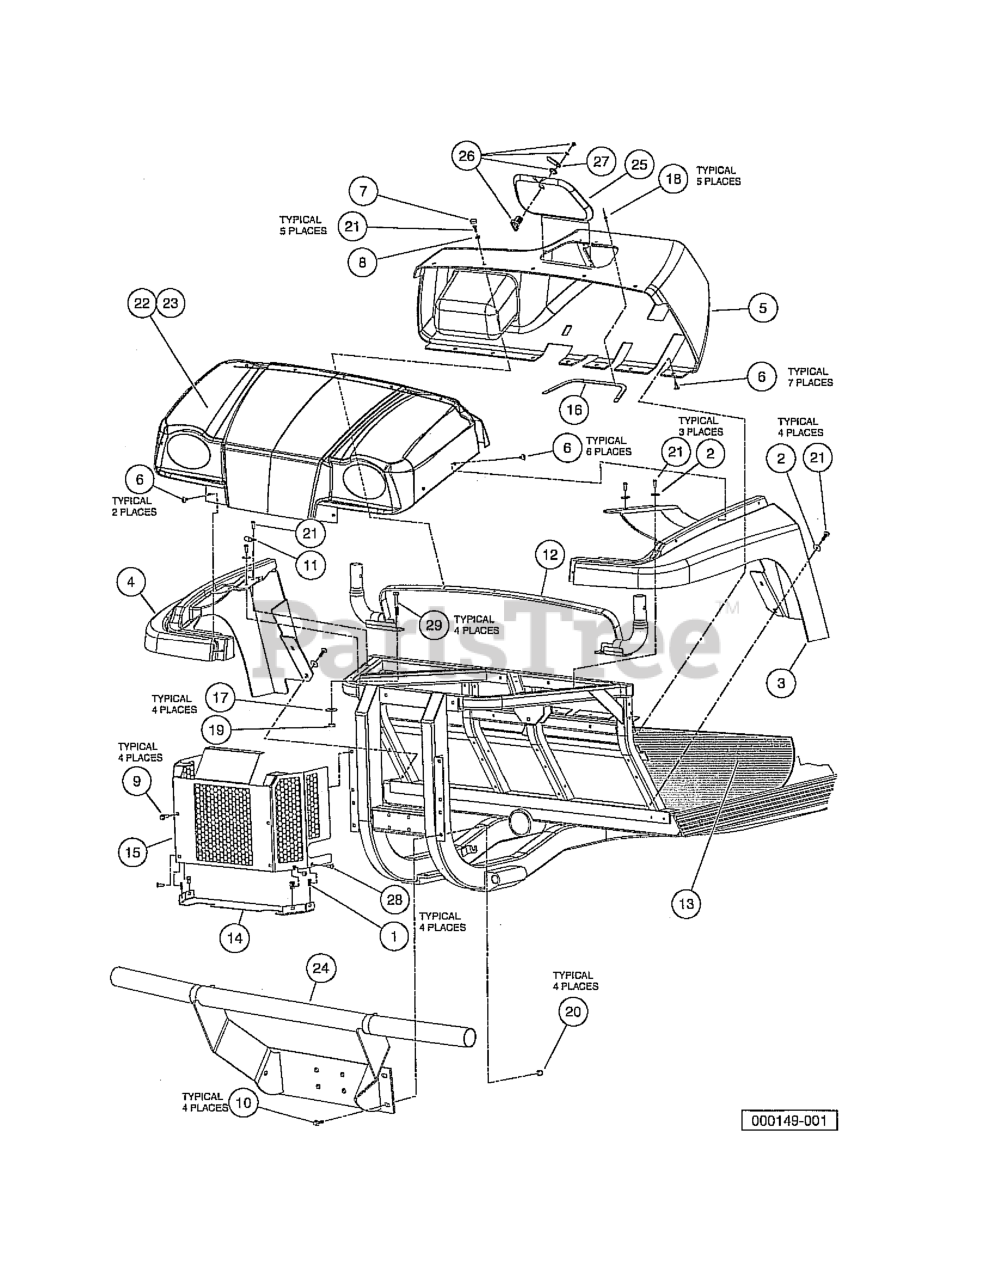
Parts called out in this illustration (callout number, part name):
1	NUT, 1/4-20 SPEED
3	FENDER, LEFT FRONT B
4	FENDER - RIGHT FRONT B
5	DASH BOARD WITH ACCESS HOLE
6	SCREW, TUFLOK PANEL, 1/4
9	SCREW, M8 X 1.25 X 30 TRI, BLK
10	BOLT - FLANGED HD, M8 X 30.0
11	P-CLAMP, INSULATED .312 IN
12	WELDMENT, SUPP, COWL, ROPS
13	MAT, FLOOR AWD
14	GUARD, RADIATOR BOTTOM
15	WELDMENT, RADIATOR GUARD
16	SUPPORT, ACCESS PANEL, DASH
17	WASHER HARD, M10
18	RIVET, .125" DIA, .311" PANEL
19	NUT FLG M10 X 1.5 MECH DEF
20	LOCK NUT, FLG M8 X 1.25 NYLON
21	SCREW, 1/4-20X1.0 PN HD TORX
22	Cowl, Camo
23	COWL, OEM, ORANGE
24	Brush Guard
25	PANEL, ACCESS, DASH
26	CAM LOCK BODY
27	LATCH, CAM, ACCESS PANEL
28	SCREW 1/4-20 X .75
29	BOLT, M10 X 1.50 X 65
